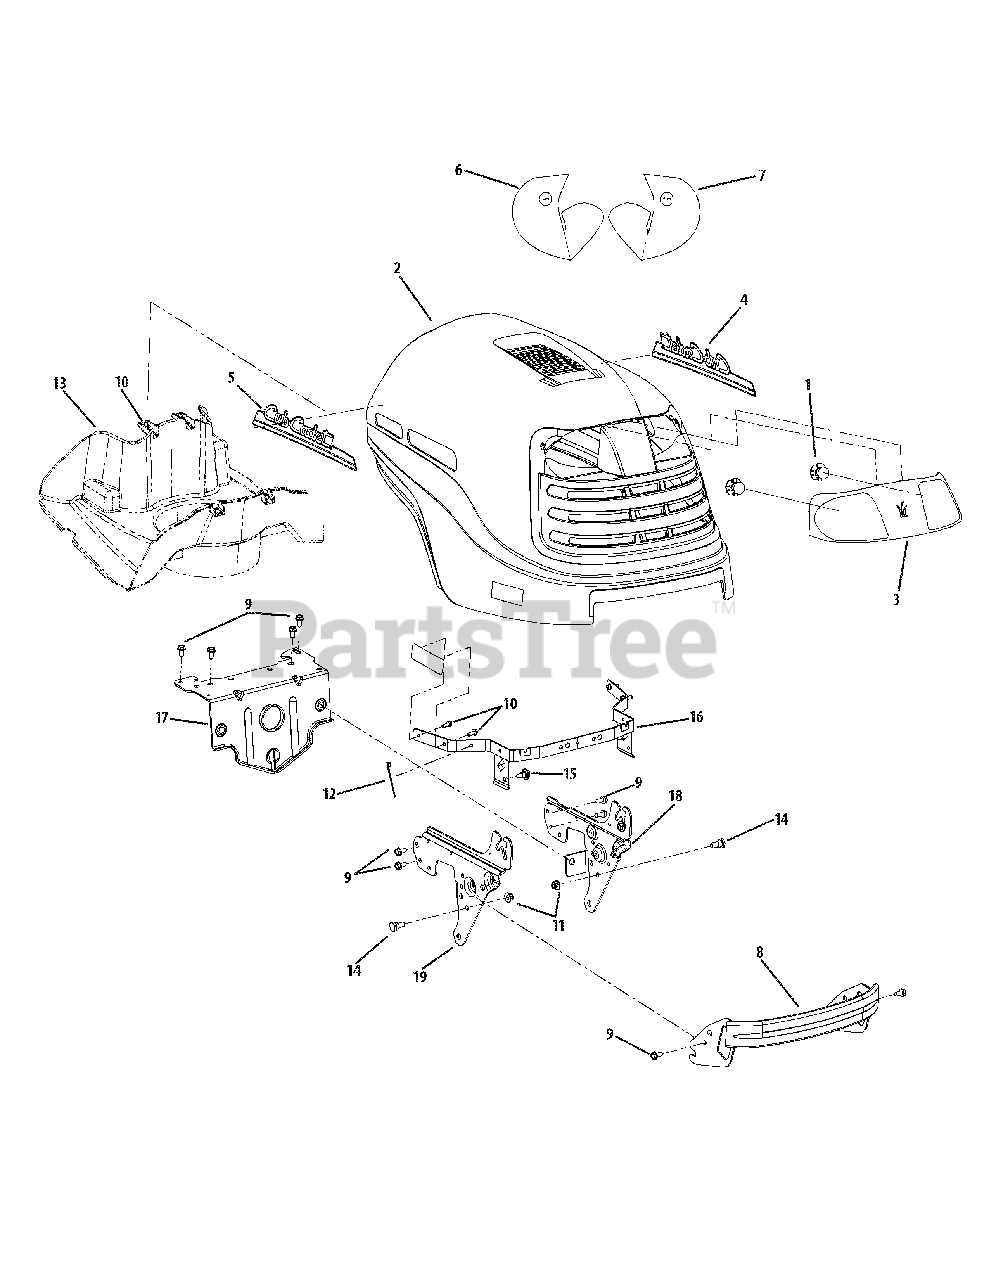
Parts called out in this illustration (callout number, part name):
1	Socket Assembly
1	Miniature Lamp, 12V
1	Lamp Socket
2	Hood Cub 1000
3	Lens, Cub 1000 Headlight
4	Label LH, Cub 1000 Heat
5	Label RH, Cub 1000 Heat
6	Label, Cub 1000 Left Lens
7	Label, Cub 1000 Right Lens
8	Bumper Assembly
9	Screw, Hex Washer, 5/16-18 x .750
10	Screw, Hex Washer, 1/4-15 x .750
11	Nut, Flange Lock, 3/8-16
12	Tie, Cable
13	Plenum, Hood
14	Bolt, Shoulder, 3/8-16 x .496 x .336
15	Screw, Shoulder, 5/16-18 x .43 x .29
16	Bracket, Hood Pivot
17	Bracket, Pivot Bar
18	Bracket, Pivot Support LH
19	Bracket, Pivot Support RH
